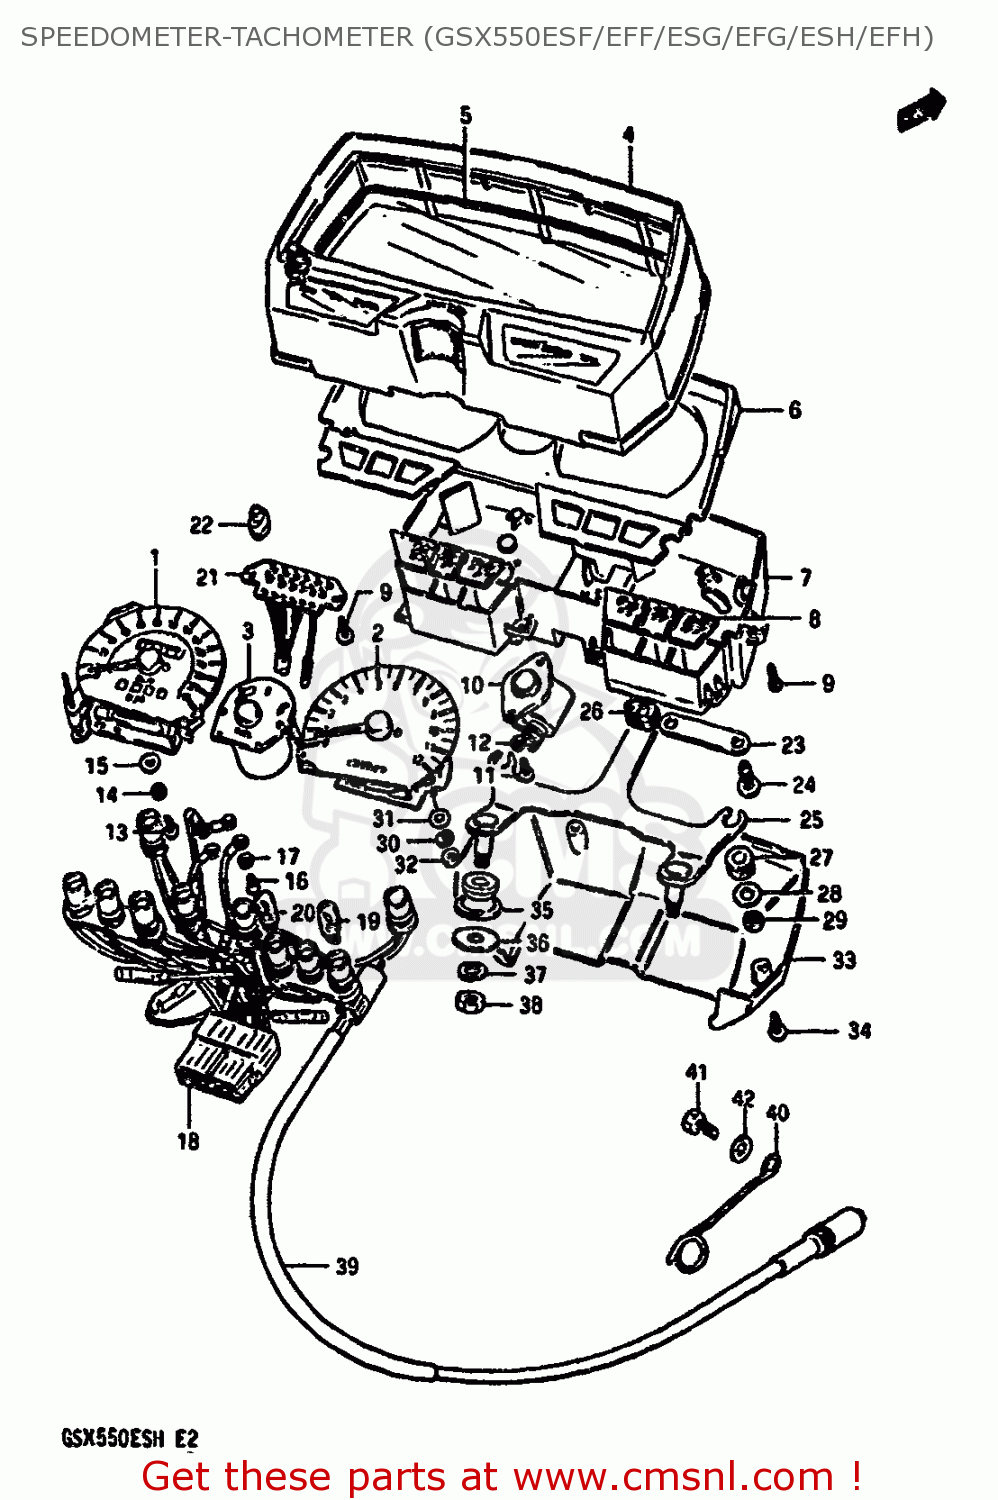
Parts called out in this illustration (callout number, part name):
1	SPEEDOMETER (KILO)
2	TACHOMETER
3	METER,FUEL
4	HOOD,METER
5	GLASS,SPEEDOMETER
6	PLATE, WINDOW
7	CASE,METER,INNER
8	LENS SET,PILOT
9	SCREW,GEAR INDICATOR
10	BOX,GEAR
11	SCREW 4X10
12	WASHER,LOCK 4M
13	SCREW
14	LOCK WASHER
15	WASHER
16	SCREW
17	WASHER
18	SOCKER
19	BULB(12V3.4W,T10,BF175-01450A)
20	BULB(12V1.7W,T10,WB121)
21	SOCKET,GEAR INDICATOR
22	BULB(14V1.12W)
23	PLATE,COUPLER
24	SCREW
25	BRACKET,METER
26	CUSHION,METER
27	CUSHION,METER
28	WASHER
29	NUT
30	WASHER,LOCK 4M
31	WASHER,SPEEDOMETER
32	NUT
33	COVER,METER,UNDER
34	SCREW
35	CUSHION,METER BRACKET
36	WASHER (8.5X20X1.6)
37	WASHER,LOCK,8.
38	NUT
39	CABLE ASSY,SPEEDOMETER
40	CLAMP,SPEEDOMETER CABLE
41	BOLT
42	WASHER
